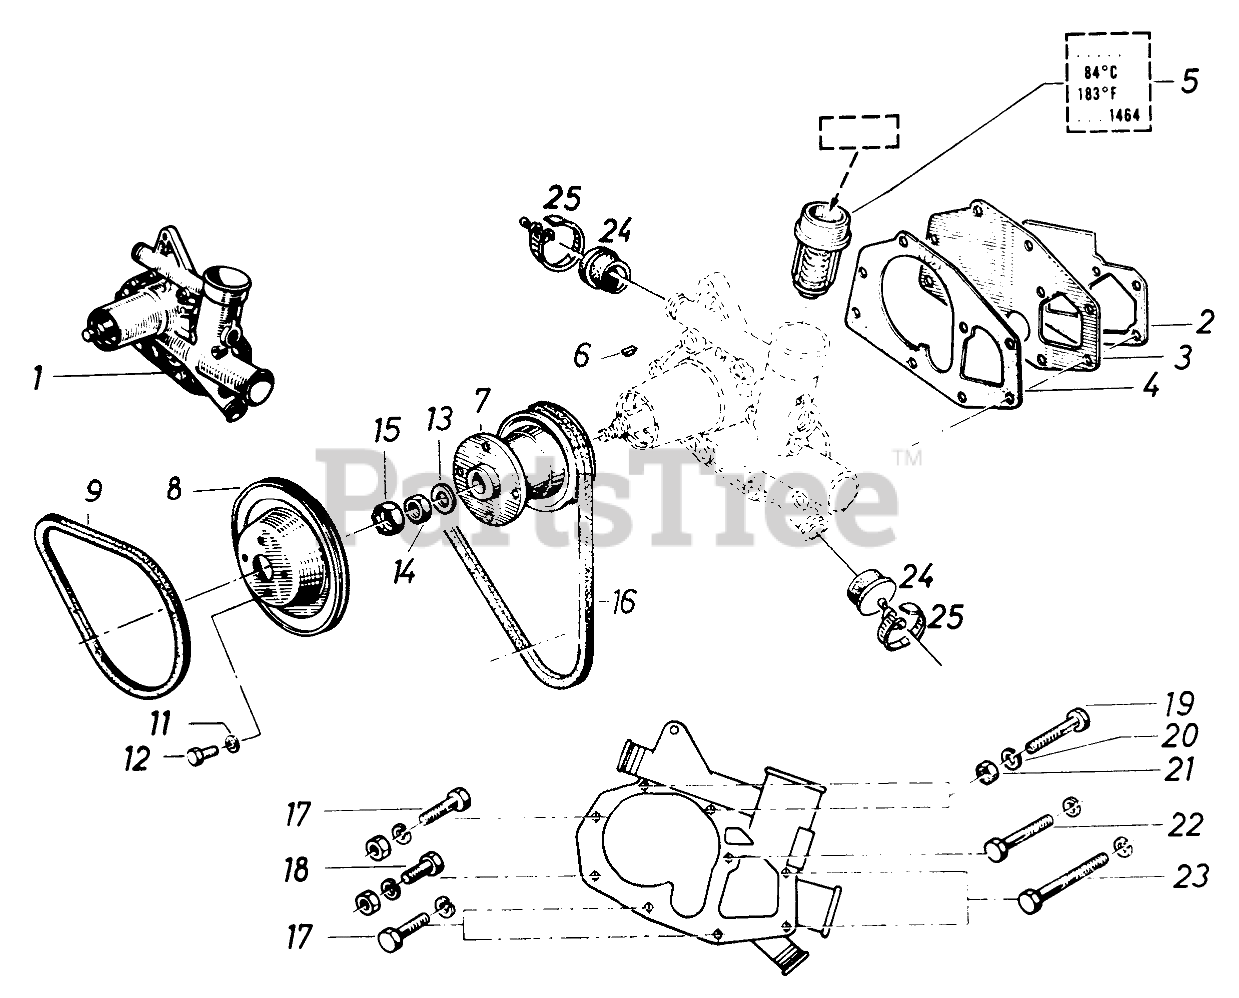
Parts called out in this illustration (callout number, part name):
1	Water Pump Cpl.
2	Gasket
3	Bracket
4	Gasket
5	Thermostat
7	Pulley
8	Pulley
9	V-Belt (9.5 X 600)
11	Washer
13	Washer
15	Lock Nut
16	V-Belt 9.5 X 675
17	Screw
19	Screw
20	Lockwasher
24	Plug, Water Pump
25	Clamp
